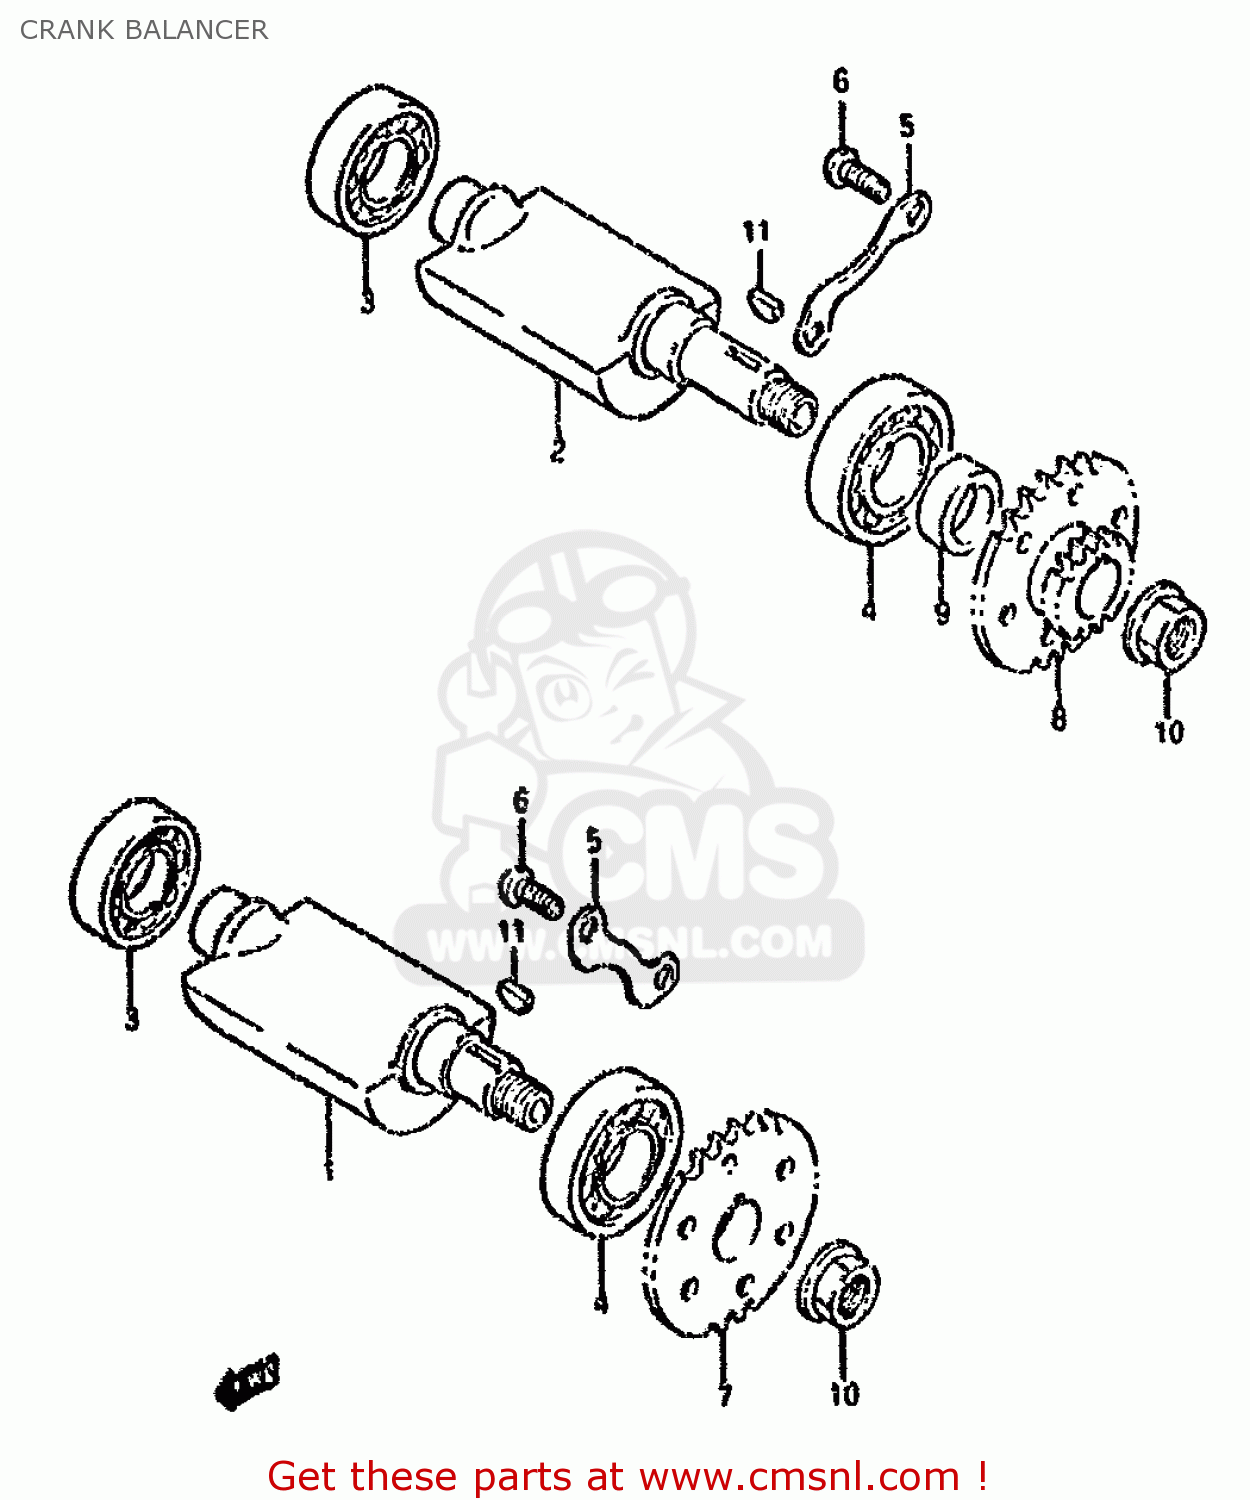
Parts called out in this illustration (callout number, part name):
1	BALANCER,CRANK FR
2	BALANCER, CRANK,REAR
3	BEARING(20X42X12)
4	BEARING(20X47X14)
5	RETAINER,CRANK BAL BEARING
6	SCREW
7	SPROCKET,BALANCER DRIVEN FR
8	SPROCKET,BAL.R
9	SPACER,CRANK BAL RR
10	NUT
11	KEY
